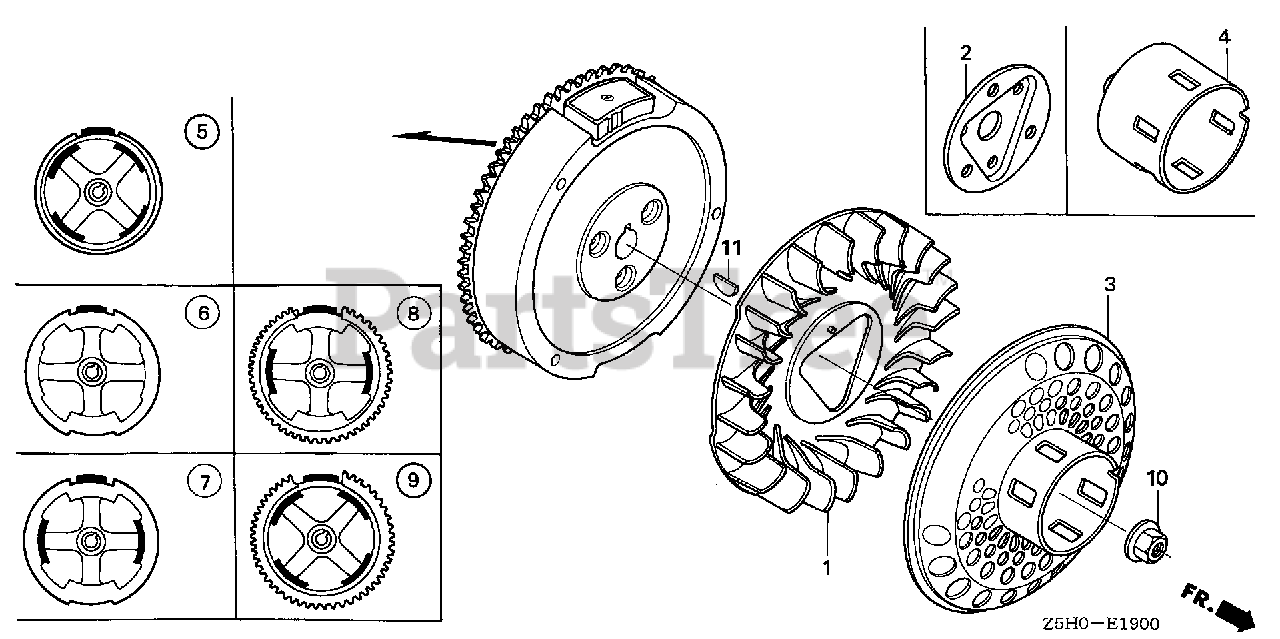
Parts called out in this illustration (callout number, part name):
1	FAN, COOLING
3	PULLEY, STARTER (SCREEN GRID)
9	FLYWHEEL (4POLE)
10	NUT, SPECIAL (16MM) (1)
10	NUT, SPECIAL (16MM)
11	KEY, SPECIAL WOODRUFF (25X18)
